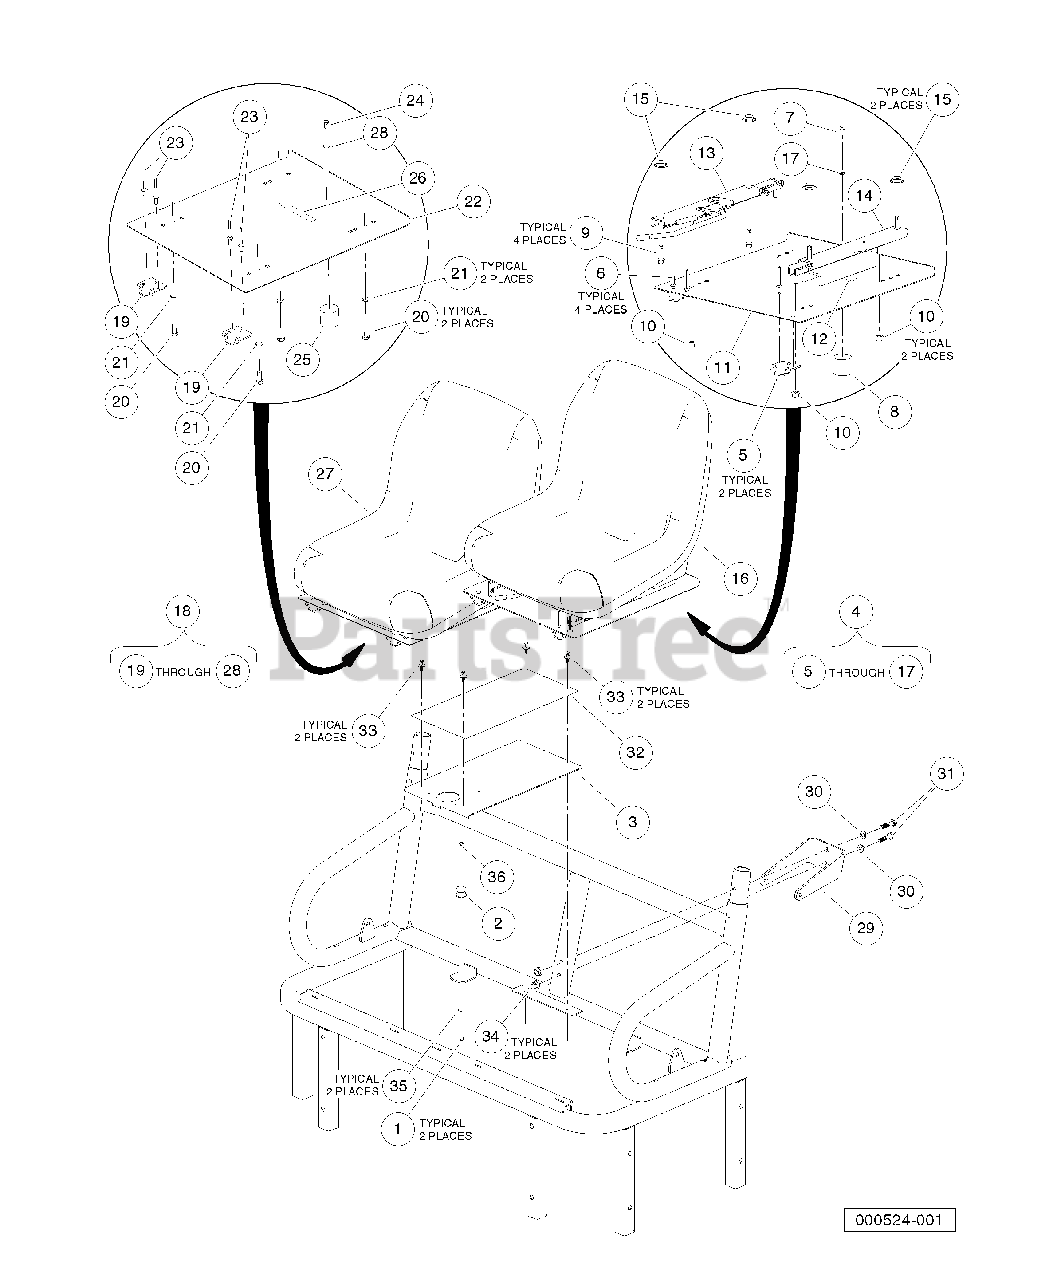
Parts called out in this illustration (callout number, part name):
1	Locknut, M6-100 Nylon Insert
2	Seat Holder Base
3	Pan, Center, Closeout
4	Asm, Bucket Seat Adjustable
5	Hinge Plate
6	Rivet, 1/4 X .438 Blind
7	Screw, 6m-1.00 X 10mm Hex Head
8	Seat Holder Cup
9	Bolt, Flange Head, M8 X 30.0
10	Nut,m8,all Metal Lock
11	Pan, Seat, Driver Asm
12	Decal, Hot Surface Warning
13	Adjuster, Forward/Aft
14	Adjuster, Slider
15	Washer, Bell
16	Seat, Bucket, Gray
17	Lockwasher, 1/4 Helical Split
18	Assembly, Bucket Seat w/Spacers
19	Hinge Plate
20	Screw, M8-125 X 22 Hex-Head
21	Lockwasher, 8mm Split
22	Pan, Seat, Passenger
23	Rivet, 1/4 X .438 Blind
24	Screw, 6m-1.00 X 10mm Hex Head
25	Seat Holder Cup
26	Decal, Hot Surface Warning
27	Seat, Bucket, Gray
28	Lockwasher, 1/4 Helical Split
29	Bracket, Seatbelt, Bolt-On
30	Washer, Hard, M10, Zn-Ni/Blk
31	Bolt, M10 X 45, Zn-Ni
32	Cover, Center Console
33	Rivet, Removable, Tuflok 1/4"
34	Nut, Flanged, M10 x 1.5, Black
35	Washer, 1/4 Type A Narrow Flat
36	Bolt, M6 X 1 X 45
